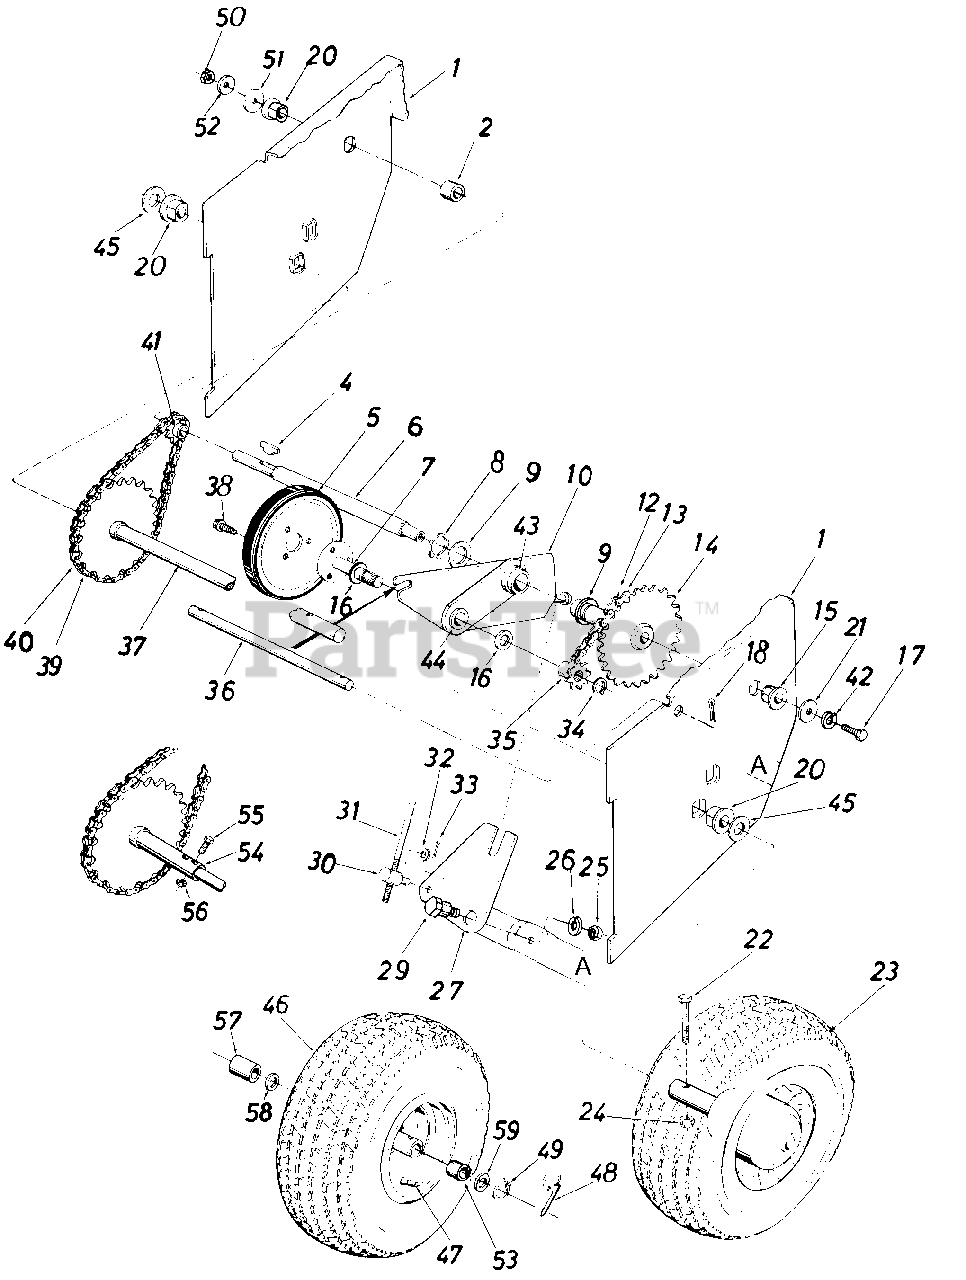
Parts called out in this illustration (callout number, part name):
1	Frame Ass'y.
2	Spacer .50" I.D. x .75" O.D. x.78" Lg.
4	#4 Hi-Pro Key 3/32 x 5/8" Dia.
5	Friction Wheel Ass'y.
6	Hex Shaft
7	Friction Wheel Mounting Plate Ass'y.
8	Snap Ring 1.00" Dia. Shaft
9	Fl-Wash. 1.00" x 1.63" O.D. x .03
10	Sliding Bracket Ass'y.
12	#41 Chain 1/2" Pitch x 35 Links
13	Master Link for #41 Chain
14	32 Teeth Sprocket Ass'y.
15	Hex Flange Brg. .630" I.D.
16	Fl-Wash. .62" I.D. x 1.00 O.D. x .06
17	Hex Lock Bolt 5/16-18 x .62" Lg.
18	Cotter Pin 3/32" Dia. x .75 Lg.*
20	Flange Brg. w/Flats .755" I.D.
21	Fl-Wash. .34" I.D. x 1.12" O.D. x .125
22	Hex Bolt 5/16-24 x 1.50" Lg.
23	Wheel Ass'y.
24	Hex Ins. Jam L-Nut 5/16-24 Thd.
25	Hex Jam Nut 3/8-16 Thd.
26	L-Wash. 3/8" I.D.
27	Shifting Linkage Bracket
29	Shld. Bolt .625" Dia. x .170" Lg.
30	Adjustment Ferrule
31	Shifting Rod 5/16" Dia. x 32.50" Lg.
32	Fl-Wash. .34" I.D. x .64" O.D x .06
33	Cotter Pin 3/32" Dia. x .75" Lg.
34	Snap Ring .562" Dia. Shaft
35	Sprocket 7 Teeth x .50" Pitch
36	Shaft .50" Dia. x 9.50" Lg.
37	28 Teeth Wheel Axle Ass'y.
38	Hex Wash. Hd. Self-Tap Scr. 5/16-24 x .50" Lg.
39	#41 Chain 1/2" Pitch x 43 Links
40	Master Link for #41 Chain
41	8 Teeth Center Sprocket
42	L-Wash. 5/16" I.D.
43	Bearing
44	Bronze Bearing
45	Fl-Wash. .76" I.D. x 1.49 O.D.
46	Wheel Assembly
47	Air Valve
48	Klick Pin
49	Snap Ring .75 Dia.
50	Hex Ins. L-Nut 1/2-20 Thd.
51	Fl-Wash. .53 I.D. x 1.25 O.D. x . 10
52	Bell-Wash. .50 I.D. x 1.0 O.D. x .075
53	Sleeve Brg.
54	32 Teeth Sprocket Hub Ass'y.
55	Hex Bolt 1/4-28 x .2
56	Hex L-Nut 1/4-28 Thd.
57	Spacer
58	Fl-Washer
59	Fl-Washer
